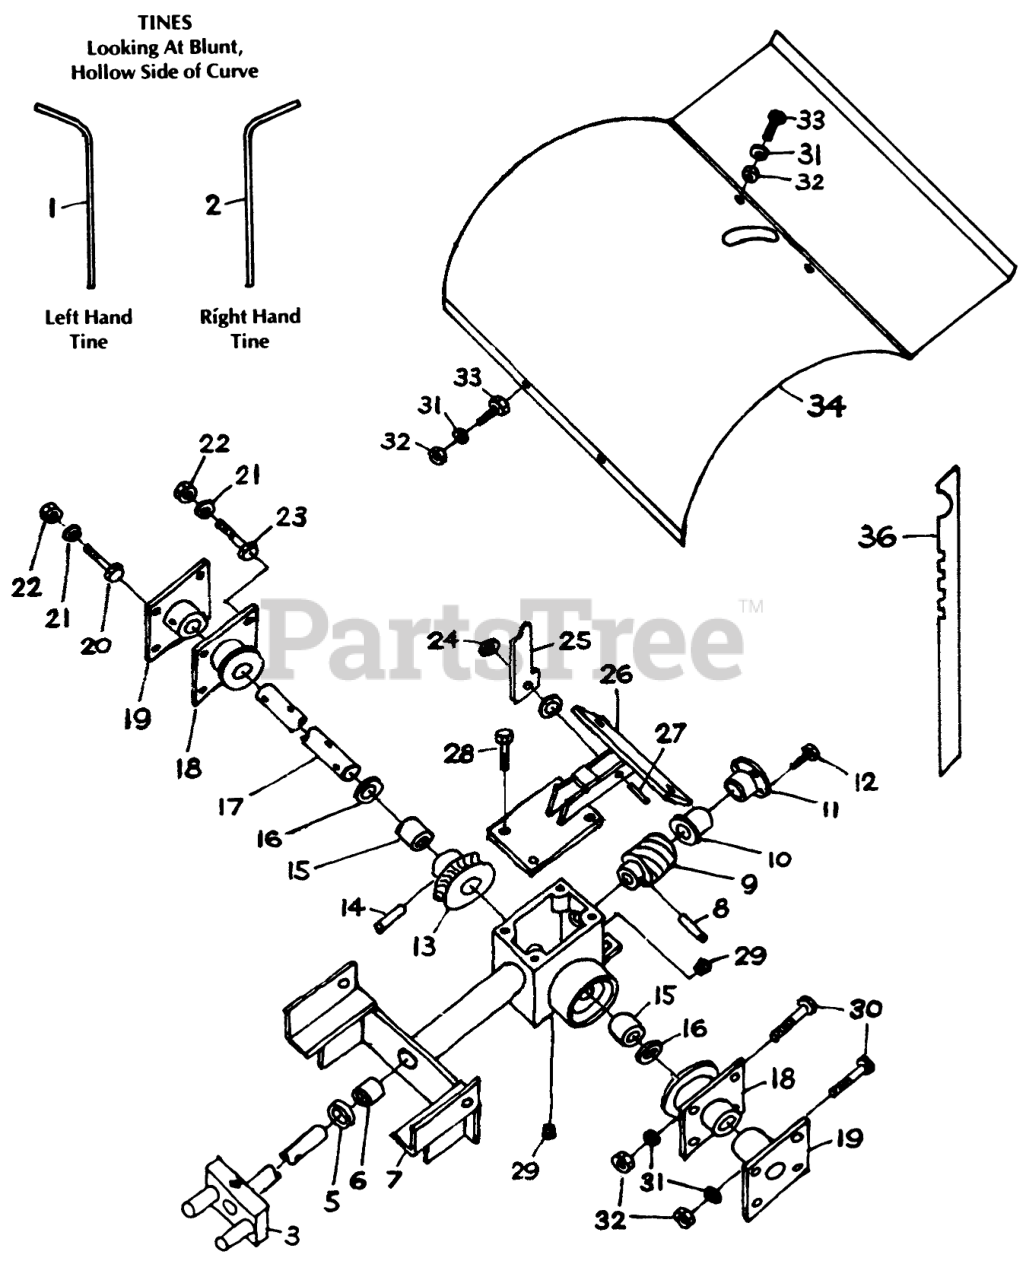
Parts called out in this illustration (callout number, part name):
1	Tine-Left Hand
2	Tine-Right Hand
3	Coupling Yoke
5	SEAL
6	BEARING
7	Frame
8	PIN-ROLL 1/4 X 1 1/4
9	WORM
10	Flanged Bearing
11	Governor Crank
12	H H C S
13	Worm Gear
14	Roll Pin 5/16 x 1 3/4
15	BEARING
16	Seal
17	SHAFT-TILLER
18	Inner Tine Hub
19	Spacer (Control Bracket)
20	BOLT
21	LOCKWASHER
22	Nut
23	Bolt
25	Lock Lever
26	Hood Bracket
27	SPIROL PIN
28	Bolt
29	PLUG 1/4 PIPE ALLEN
30	Bolt 5/16-18 x 2
31	Lockwasher
32	Nut
33	Bolt
34	Tiller Hood 15"
36	STICK-DRAG
